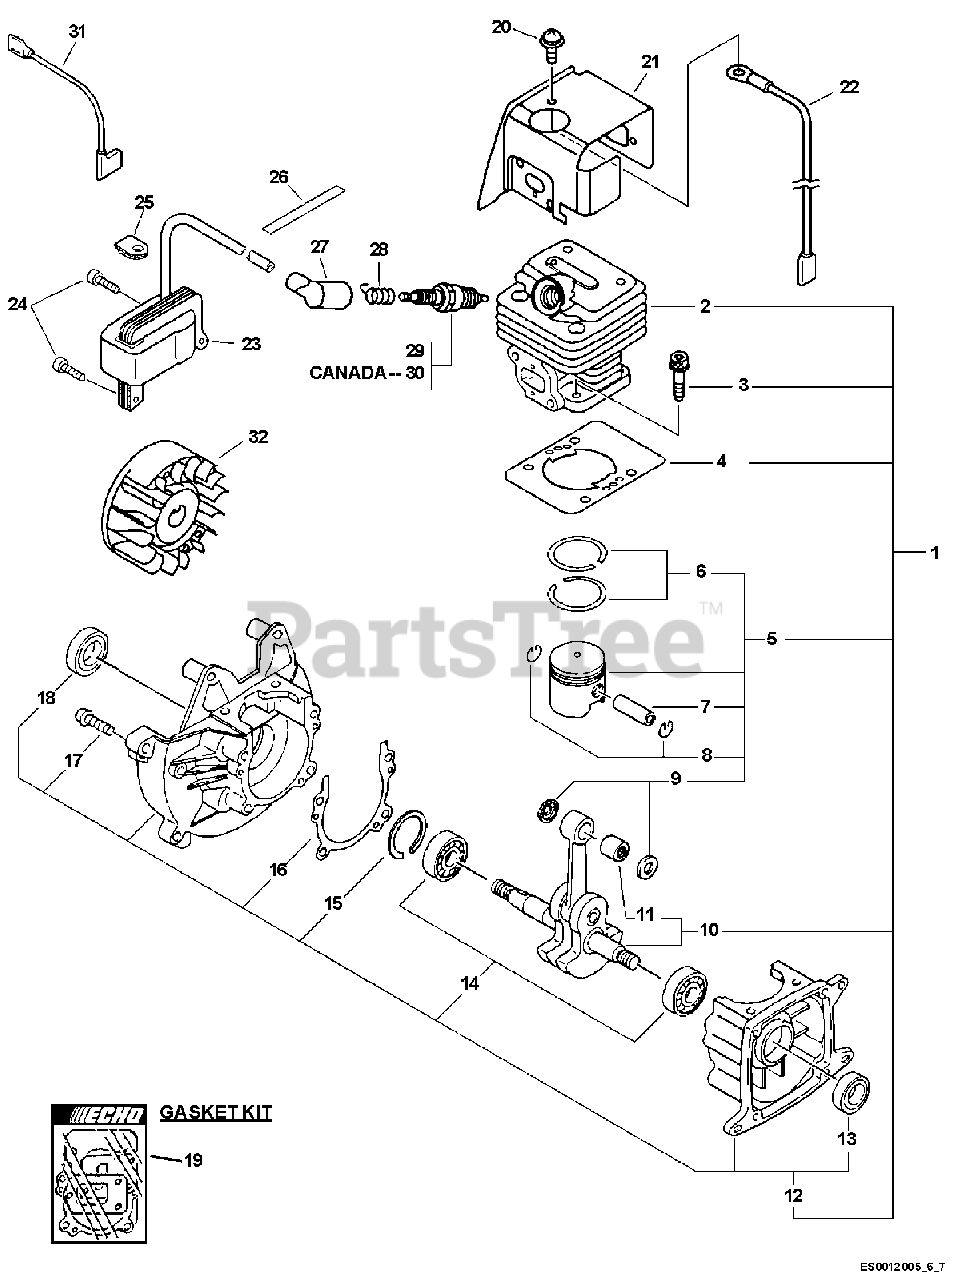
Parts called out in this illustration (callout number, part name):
1	SHORT BLOCK -- SB1062
2	CYLINDER
3	SCREW - 5X22
4	GASKET, CYLINDER
5	PISTON KIT
6	RING, PISTON
7	PIN, PISTON
8	RING, RETAINING
9	SPACER, PISTON
10	CRANKSHAFT ASSY
11	BEARING, NEEDLE - 8
12	CRANKCASE KIT
13	SEAL, OIL
14	BEARING, BALL - 6001C3
15	RING, RETAINING - 28
16	GASKET, CRANKCASE
17	SCREW - 5X25
18	SEAL, OIL - 12
19	GASKET KIT
20	SCREW - 5X10
21	SHIELD, CYLINDER
22	LEAD - GROUND
23	COIL, IGNITION
24	SCREW - 5X16
26	LABEL - SPARK PLUG -- BPM-8Y
27	CAP, SPARK PLUG
28	TERMINAL, SPARK PLUG CAP
29	SPARK PLUG -- BPM-8Y
30	SPARK PLUG -- BPMR-8Y
31	LEAD - IGNITION
32	FLYWHEEL
